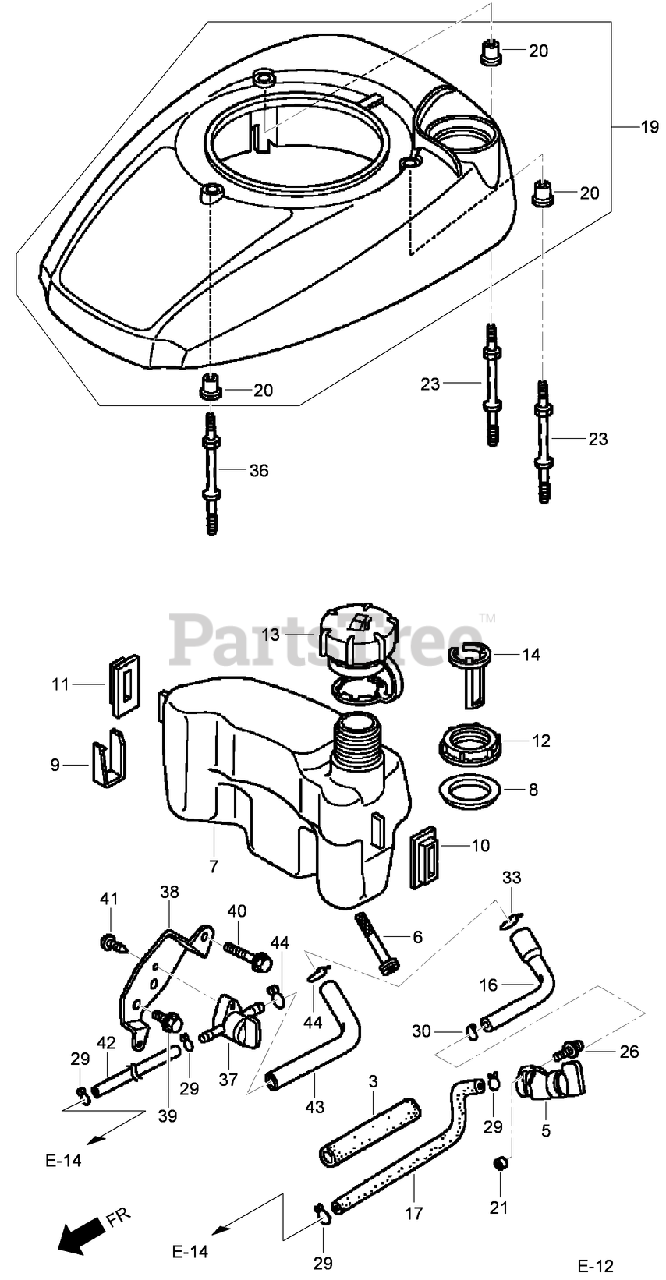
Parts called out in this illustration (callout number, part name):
3	SUPPORTER-RUBBER (107 mm)
5	PETCOCK ASM (engine serial numbers up to 6901760)
6	FILTER-FUEL
7	TANK-FUEL (engine serial numbers up to 6183839)
7	TANK-FUEL (engine serial numbers starting at 6183840)
8	SEAL-NECK, FUEL FILLER
9	CLIP-MOUNTING, TANK
10	RUBBER A-MOUNTING, TANK
11	RUBBER B-MOUNTING, TANK
12	NUT-MOUNTING, TANK
13	FUEL TANK CAP ASM
14	GAUGE-LEVEL, FUEL
16	TUBE-TANK, FUEL (engine serial numbers up to 6901760)
17	TUBE-FUEL (engine serial numbers starting at 6901760)
19	COVER-FAN (NH1) (BLACK) (engine serial numbers up to 6702082)
19	COVER-FAN (T89) (CRAFTSMAN RED) (engine serial numbers up to 6702082)
19	COVER-FAN (T93) (HUSQVARNA GRAY) (engine serial numbers up to 6702082)
19	COVER-FAN (T98) (M T D RED) (engine serial numbers up to 6702082)
19	COVER-FAN (NH1) (BLACK) (engine serial numbers starting at 6702083)
19	COVER-FAN (T89) (CRAFTSMAN RED) (engine serial numbers starting at 6702083)
19	COVER-FAN (T93) (HUSQVARNA GRAY) (engine serial numbers starting at 6702083)
19	COVER-FAN (T98) (M T D RED) (engine serial numbers starting at 6702083)
20	COLLAR-COVER, FAN
21	COLLAR-PETCOCK, FUEL (engine serial numbers up to 6901760)
23	BOLT-STUD (H=42.5MM)
26	SCREW-WASHER (5X10)
29	CLIP-TUBE (B8)
30	CLIP-TUBE (B10)
33	CLIP-TUBE (C11) (engine serial numbers up to 6901760)
36	BOLT-STUD (H=42.5MM)
37	PETCOCK ASM (engine serial numbers starting at 6901761)
38	STAY-PETCOCK (engine serial numbers starting at 6901761)
39	BOLT-FLANGE (6X12) (C T200)
40	BOLT-FLANGE (6X28) (C T200) (engine serial numbers starting at 6901761)
41	SCREW-TAPPING (5X12) (P O) (engine serial numbers starting at 6901761)
42	FUEL-HOSE, BULK (4.5X3000) (4.5X110) (engine serial numbers starting at 6901761)
43	FUEL-HOSE, BULK (7.5X8000) (7.3X160) (engine serial numbers starting at 6901761)
44	CLIP-TUBE (B12) (engine serial numbers starting at 6901761)
